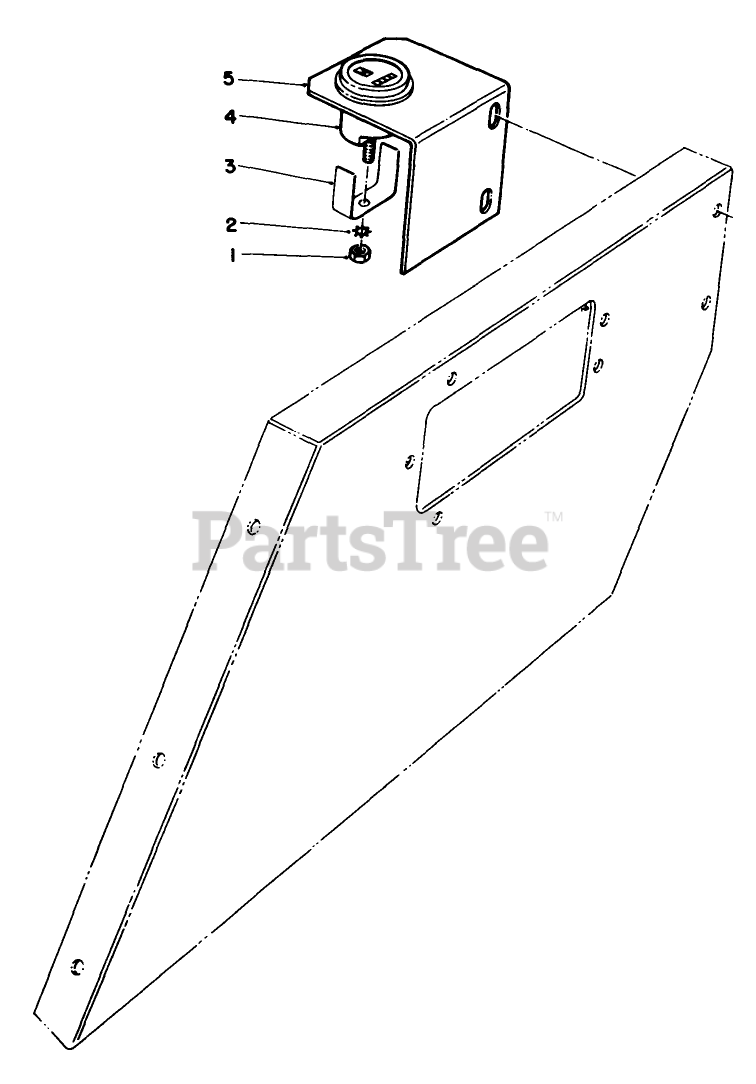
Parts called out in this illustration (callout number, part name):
1	NUT-HEX
2	WASHER-LOCK, INT
3	BRACKET F/W
4	Hour Meter (Incl. Ref. #1-3)
5	HR.METER BRKT. R
